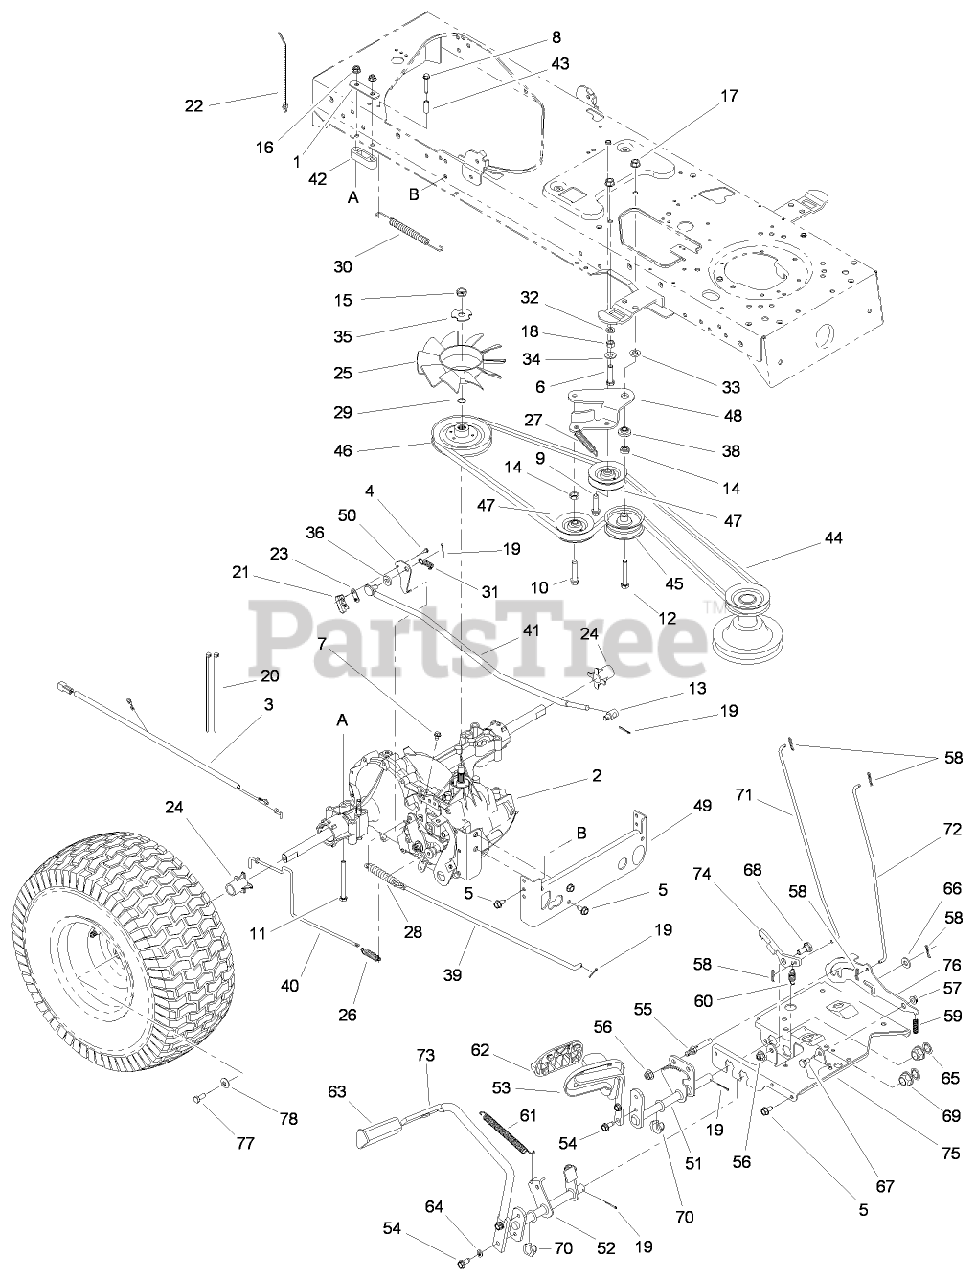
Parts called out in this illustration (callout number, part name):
1	BRACKET-MOUNTING, TRANSMISSION
2	HYDRO TRANSMISSION ASM
3	HARNESS ASM
4	SCREW-HWHTF
5	SCREW-TAP
6	SCREW-HH
7	SCREW-TAP
8	SCREW-HWH
9	SCREW-TAP
10	SCREW-TAP
11	SCREW-HH
12	SCREW-HH
13	FERRULE
14	NUT-JAM
15	NUT-JAM
16	NUT-LOCK, FLANGE
17	NUT-LOCK, FLANGE
18	NUT-LOCK, FLANGE
19	PIN-COTTER
20	TIE-CABLE
21	SWITCH-SPRING, SHORT
22	TIE-CABLE
23	PLATE-INSULATOR
24	SLEEVE
26	SPRING-EXTENSION
27	SPRING-EXTENSION
28	SPRING-EXTENSION
29	RING-WIRE
30	SPRING-EXTENSION
31	SPRING-EXTENSION
32	WASHER-LOCK
33	WASHER-FLAT
34	WASHER-FLAT
35	WASHER-LOCK
36	WASHER-FLAT
38	SPACER-SHOULDER
39	ROD-BRAKE
40	ROD-HYDRO
41	ROD-CONTROL
42	SPACER-TRANSAXLE
43	SPACER
44	BELT-V
45	PULLEY-IDLER, FLAT
46	PULLEY-INPUT
47	PULLEY-IDLER, Y TYPE
48	BRACKET-IDLER, CENTER DOUBLE
49	BRACKET-TORQ, TRANSMISSION
50	BRACKET-ACTUATOR
51	CONTROL ASM
52	SPEED CONTROL ASM
53	CONTROL PEDAL ASM
54	SCREW-HWH
56	NUT-LOCK, FLANGE
57	NUT-LOCK, FLANGE
58	PIN-COTTER
59	SPRING
60	SPRING-EXTENSION
61	SPRING-EXTENSION
62	PAD-PEDAL
63	PAD-BRAKE
64	WASHER-LOCK
65	WASHER-FLAT
66	WASHER-FLAT
67	BOLT-SHOULDER
68	BOLT-SHOULDER
69	BEARING-FLANGE
70	BEARING-FLANGE, HEX (SPLIT)
71	ROD-BRAKE, LOCK
72	ROD-CONTROL, CRUISE
73	PEDAL-BRAKE
74	LATCH-CRUISE
75	BRACKET-SUPPORT, STEERING
76	BRACKET-LOCKOUT
77	SCREW-HH
78	WASHER-BELL
